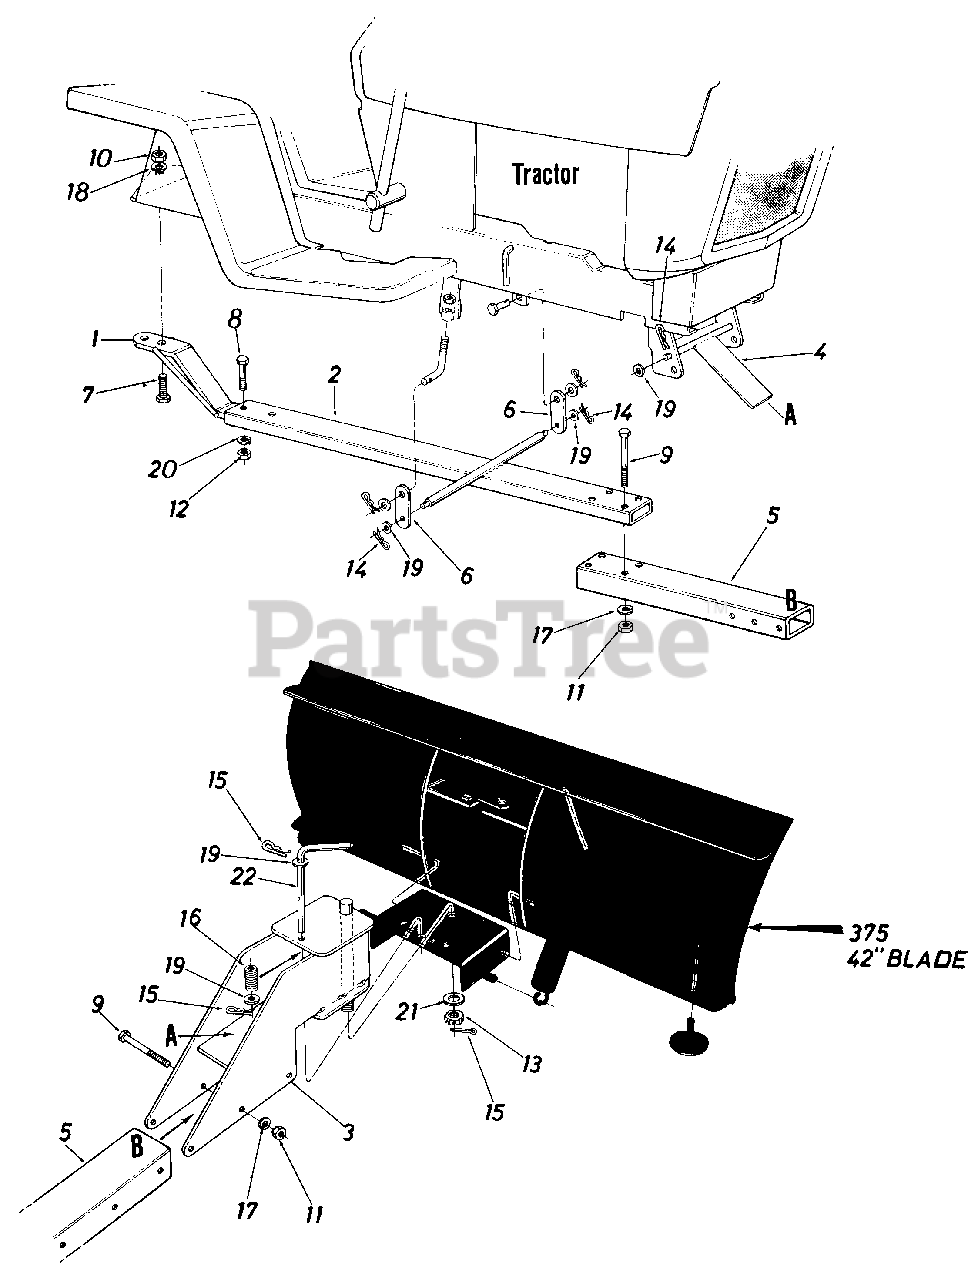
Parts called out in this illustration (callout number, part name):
1	Hanging Bracket Ass'y.
2	Lift Shaft Ass'y.
3	Pivot Bracket Ass'y.
4	Guide Plate Ass'y.
5	Rectangular Tubing
6	Lift Linkage
7	Hex Bolt 5/8-18 x 1.31 " Lg.
8	Hex Bolt 1/2-20 x 1.50" Lg.*
9	Hex Bolt3/8-24 x 3.75" Lg.*
10	Hex Ins. L.-Nut 5/8-18 Thd.
11	Hex Nut 3/8-24 Thd.*
12	Hex Jam Nut 1/2-13 Thd.
13	Castle Nut 3/4-16 Thd. (Grade 5)
14	Inter Cot. Pin 1/2" Dia.
15	Cotter Pin 5/32 x 1.25" Lg.*
16	Compression Spring
17	L.-Wash. 3/8" I.D.*
18	Fl.-Wash..64" I.D. x 1.25" O.D.
19	Fl.-Wash. .510" I.D. x 1.0" O.D.
20	L.-Wash. 1/2" I.D.*
21	Fl.-Wash .812" I.D. x 1.469" O.D.
22	Handle Pivot Brkt.
